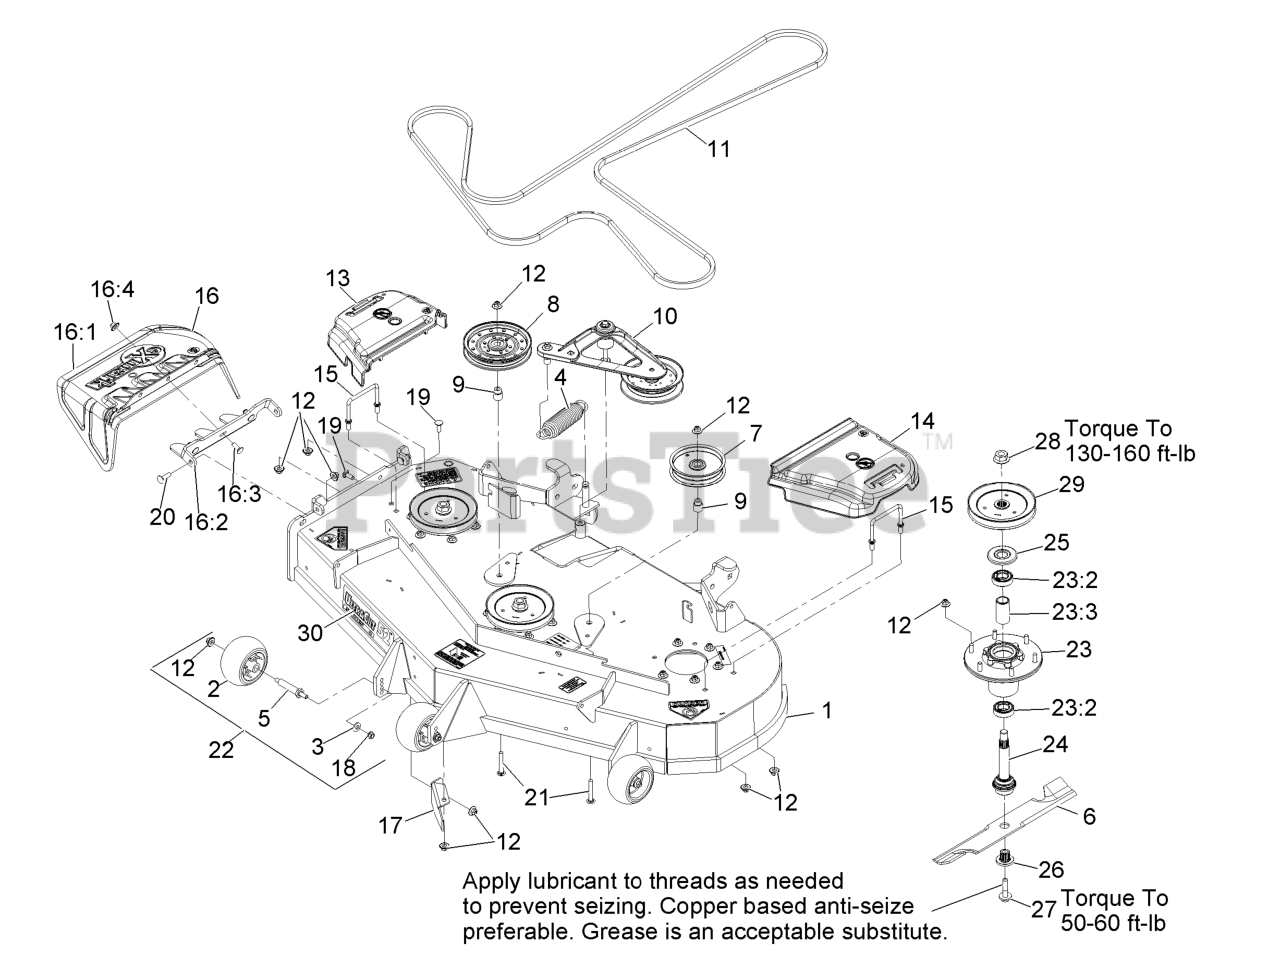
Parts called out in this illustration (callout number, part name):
1	ASM,DECK W/ DECALS 52
2	ROLLER-SCALP, ANTI
3	WASHER-BELLEVILLE
7	PULLEY-IDLER
9	BUSHING-IDLER
10	DECK IDLER ASM
11	BELT,V-B X 186.00"
12	Nut-Nyloc 3/8-16 Flg
13	COVER-BELT, RH
14	COVER-BELT, LH
15	WIREFORM-COVER
16	ASM,DISCHARGE CHUTE
16:1	CHUTE,DISCHARGE
16:2	BRACKET,DISCHARGE CHUTE
16:3	SCREW-CARR
16:4	Nut-Nyloc 3/8-16 Flg
17	BAFFLE,DISCHARGE 52/60
18	NUT-HHF, WHIZ
19	SCREW-CARR
20	Bolt-Carriage 3/8-16 X 1 1/4
21	SCREW-CARR
23	ASM-CUTTER HSG WITH BEARINGS
23:2	BEARING-BALL
23:3	SPACER-BEARING
24	ASM-SPINDLE AND SEAL
25	GUARD,BEARING TOP .989
26	BUSHING,SPLINED
27	SCREW,SEMS 1/2-20 X 2.19
28	NUT-FLANGE
29	SHEAVE,BLADE DRIVE 6.50
30	DECAL,ULTRACUT 52 SERIES
